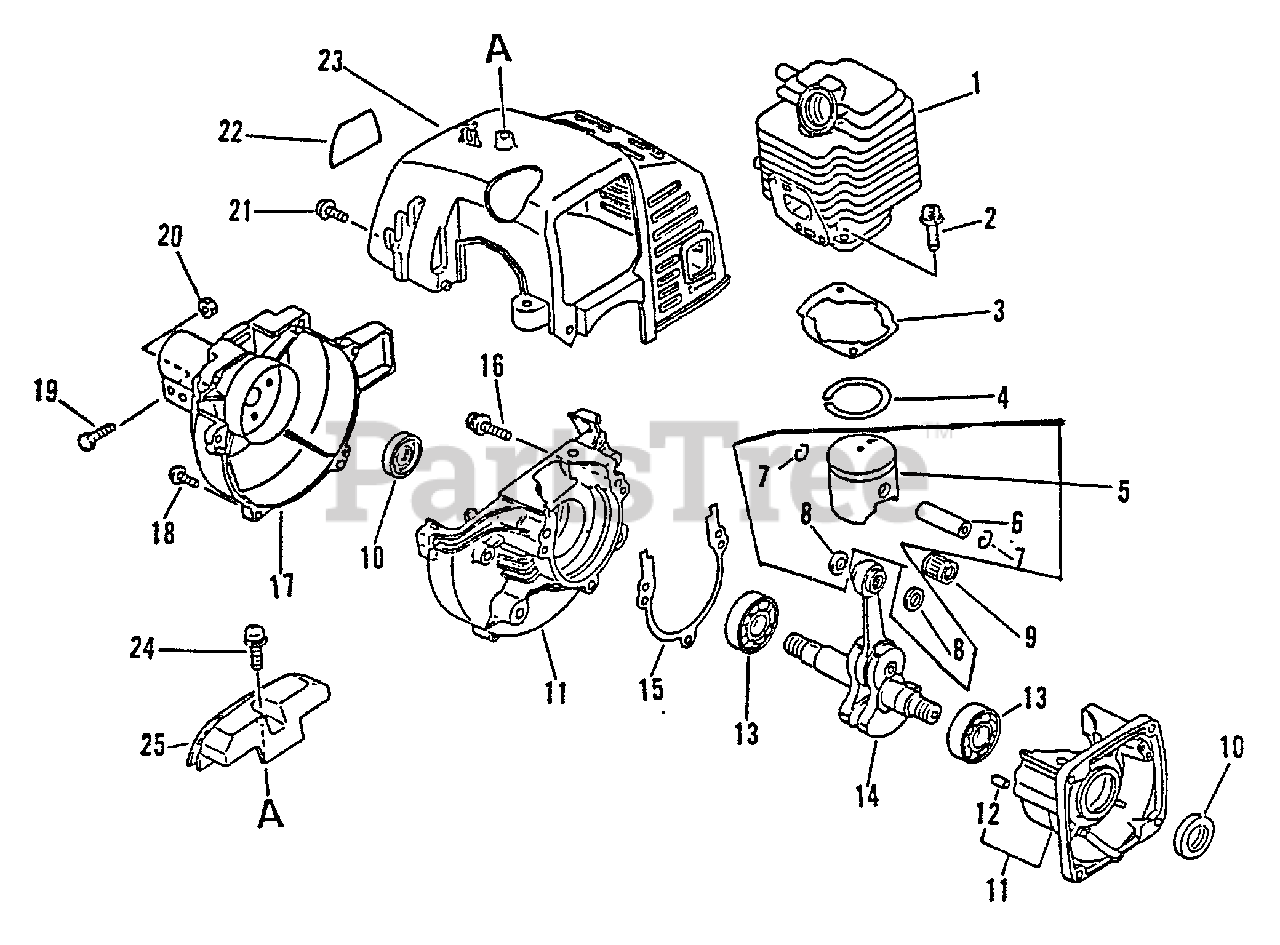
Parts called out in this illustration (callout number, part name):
1	CYLINDER
2	SCREW - 5X22
3	GASKET, CYLINDER
4	RING, PISTON
5	PISTON KIT
6	PIN, PISTON
7	RING, RETAINING
8	SPACER, PISTON
9	BEARING, NEEDLE
10	SEAL, OIL
11	CRANKCASE KIT
12	PIN - LOCATING
13	BEARING, BALL - 6201
14	CRANKSHAFT ASSY
15	GASKET, CRANKCASE
16	SCREW - 5X28
17	FAN CASE ASSY
18	SCREW - 5X18
19	BOLT - 5X28
20	NUT - 5 -- SQUARE
21	SCREW - 4X12
22	LABEL - MODEL
23	COVER, ENGINE - GRAY
24	SCREW - 5X16
25	GUARD, TOP - BLACK
